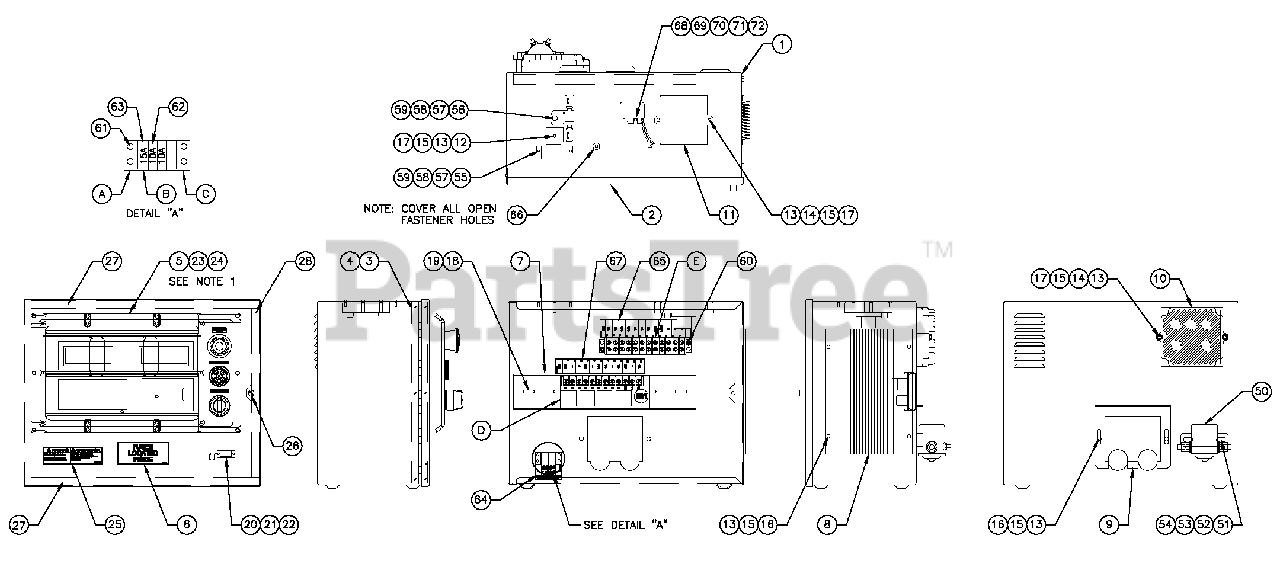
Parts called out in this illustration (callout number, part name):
1	ENCLH/G CONTROL PANEL
2	COVER CONTROL PANEL
3	HINGE CONTINUOUS H PANEL
4	RIVET POP .125X.275SS
5	ASSY PROGRAMMED H-100
6	DECAL FUSES LOCATED INSIDE
7	RAIL SNAPTRACK PCB HOLDER BULK
8	ASSY PCB 10A UL BATT CHRGR12V
9	PLATE HARNESS CLAMP
10	ASSY PCB PWR AVRW/AMP HEADER
11	ASSY PCB BOSCH GOV DRIVER
12	DIO BRIDGE 25A 600V
13	WASHER LOCK M5
14	SCREW PPHM M5-0.8X 30 SS
15	WASHER FLAT M5
16	SCREW HHPMM5-0.8X 12
17	NUT HEX M5-0.8 G8 YEL CHR
18	WASHER FLAT M4
19	SCREW PHTT M4-0.7 X 10 ZYC
20	CONN DUST CAP W/CHAIN DB9
21	WASHER FLAT M3.5
22	SCREW PHTT M3.5-0.6X 10
23	SCREW PPHM M4-0.7X 8 BLX OX
24	WASHER LOCK #8-M4
25	DECAL WRN BATT CHRG 12/24V BI
26	M5-0.8 CAPTIVE PANEL KNLD HD
27	SEAL COVER 3 .1 8X 1 2 .7X 3 8 2
28	SEAL COVER 3 .1 8X 1 2 .7X 2 8 3
50	RELAY CONTACTOR 12VDC
51	SCREW HHC 1/4-20 X 3/4 G5
52	WASHER FLAT M 6 - 1/4
53	WASHER LOCK M6 -1 /4
54	NUT HEX 1/4-20 STEEL
55	CIRCT BRK 7 X 1 ETA 46-500-P
56	RES WW 15R 5 * 25W QK CONN
57	WASHER LOCK M3
58	NUT HEX M3-0.5 G8 YEL CHR
59	WASHER FLAT M3
60	SCREW PHTT #6-32 X 5/8 ZYC
61	SCREW PHTT #6-32 X 3/8 ZYC
62	FUSE ATO TYPE 10 AMP (RED)
63	FUSE ATO TYPE 15 AMP (BLUE)
64	DECAL CPL CONTROL PANEL FUSES
65	DECAL CPL 5.4/6.8LTB3
66	SEAL WEATHER .45" DIA
67	DECAL CPL 5.4/6.8L RELAY BOARD
68	ASSY PCB CAM TO DIST SENSOR
69	SCREW PPHM M5-0.8X 12ZNC
70	WASHER FLAT M5
71	WASHER LOCK M5
72	NUT HEX M5-0.8 G8 CLEAR ZINC
A	ADPTR RH SIDE WICKMANN 178.6191
B	HOLDER FUSE WICKMANN 178.6150
C	ADPTR LH SIDE WICKMANN 178.6192
D	ASSY PCB G-PANEL RELAY 12VDC
E	BLOCK TERM 2 0A 12 X 6 X 1100V
